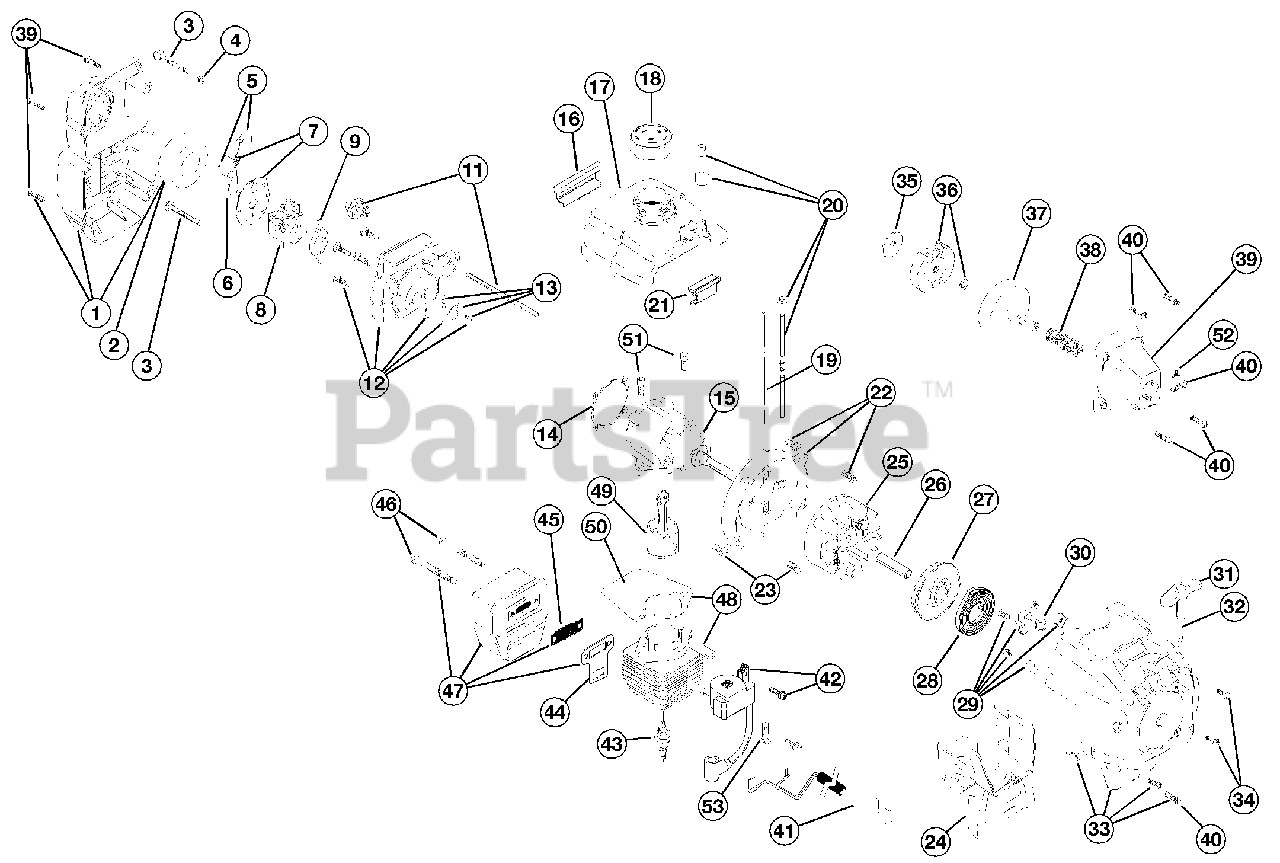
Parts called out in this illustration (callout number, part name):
1	Carburetor/Air Cleaner Cover Assembly
2	Air Cleaner Filter
3	Carburetor Mounting Screw Assembly
4	Wavey Washer
5	Choke Knob & Screw
6	Choke Lever Assembly
7	Choke Plate Assembly
8	Carburetor Assembly
9	Carburetor Gasket
10	Carb Mount Screw
11	Primer & Hose Assembly
12	Carb Mount Assembly
13	Reed Assembly
14	Carburetor Mount Gasket
15	Crank Case Service Assembly
16	Rear Mounting Pad
17	Fuel Tank Assembly
18	Fuel Cap Assembly
19	Fuel Return Line
20	Fuel Line Assembly
21	Front Mounting Pad
22	Shroud Assembly
23	Shroud Screw
24	Shroud Extension & Stand
25	Flywheel Assembly
27	Recoil Pulley Assembly
28	Recoil Spring
29	Pulley Retainer Assembly
30	Rope Guide
31	Pull Handle
33	Starter Housing Assembly
34	Housing Screw
35	Clutch Washer
36	Clutch Rotor Assembly
37	Clutch Drum Assembly
39	Clutch Cover Assembly
40	Cover Screw
41	Wire Lead
42	Module Assembly
43	Spark Plug
44	Exhaust Gasket
45	Spark Arrestor
46	Muffler Mounting Bolt Assembly
47	Muffler Assembly
48	Cylinder Assembly
49	Piston and Rod Assembly
50	Cylinder Gasket
51	Cylinder Bolt
52	Anti-Rotation Screw
53	Ground Tab
